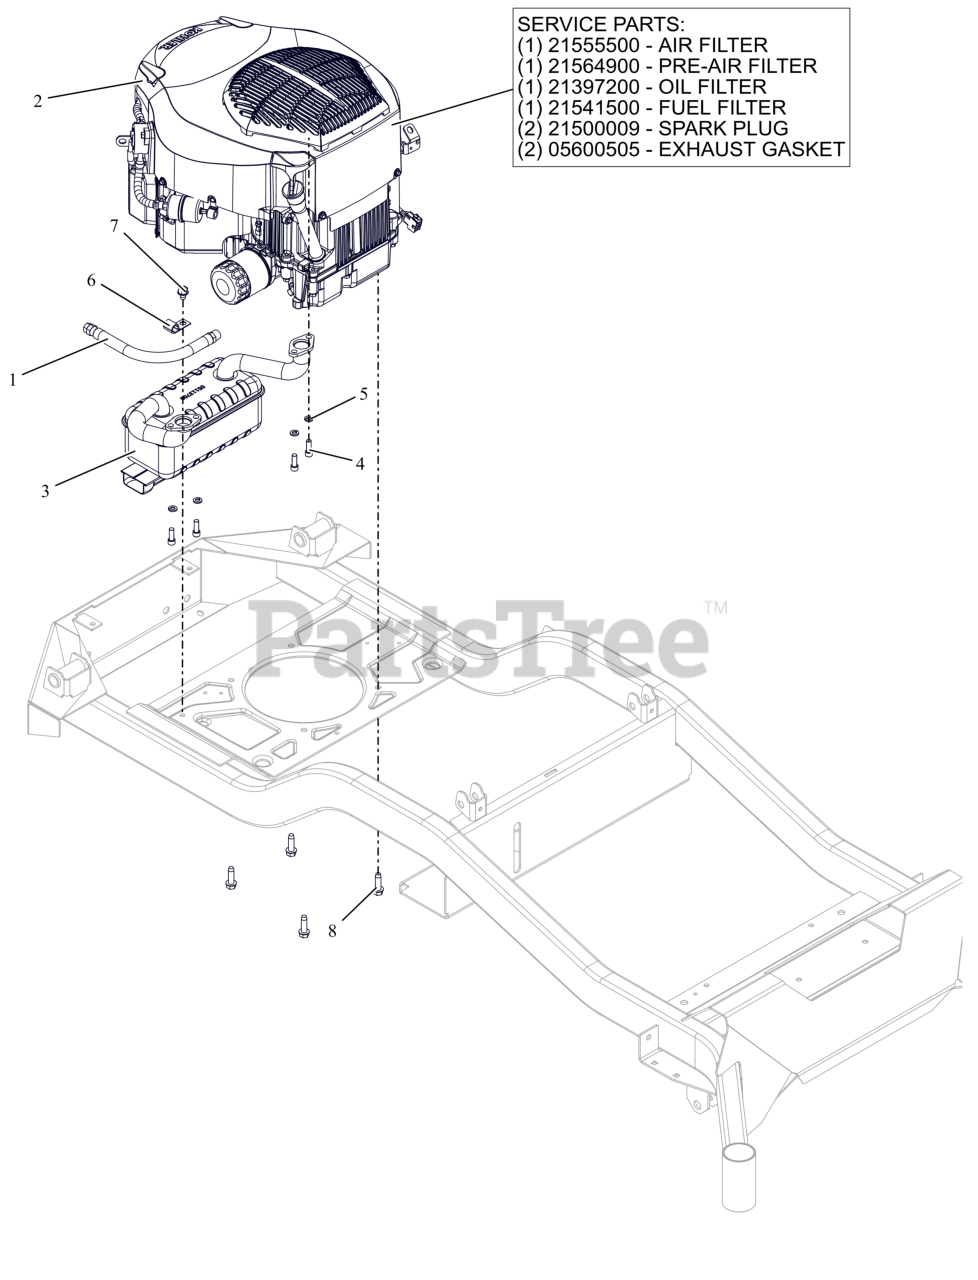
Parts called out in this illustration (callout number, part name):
1	Hose, Oil Drain
2	ENGINE, KOHLER - KT730
2	AIR CLEANER, KOHLER
2	PRE-CLEANER, KOHLER
2	FILTER, OIL - KOH CV20
2	FILTER, FUEL
2	PLUG, SPARK KOHLER
2	GASKET, MUFFLER COURAGE TWIN
3	MUFFLER, KOHLER
4	SCR-CAP .31-18X.88 S/HD G8 ZCC
5	WSHR,LK-REG .312X.078 ZCC
6	J-CLAMP
7	SCR,TAP .375-16X.50 HWH TR ZCC
8	SCR,TAP .375-16X1.25HWH TR ZCC
